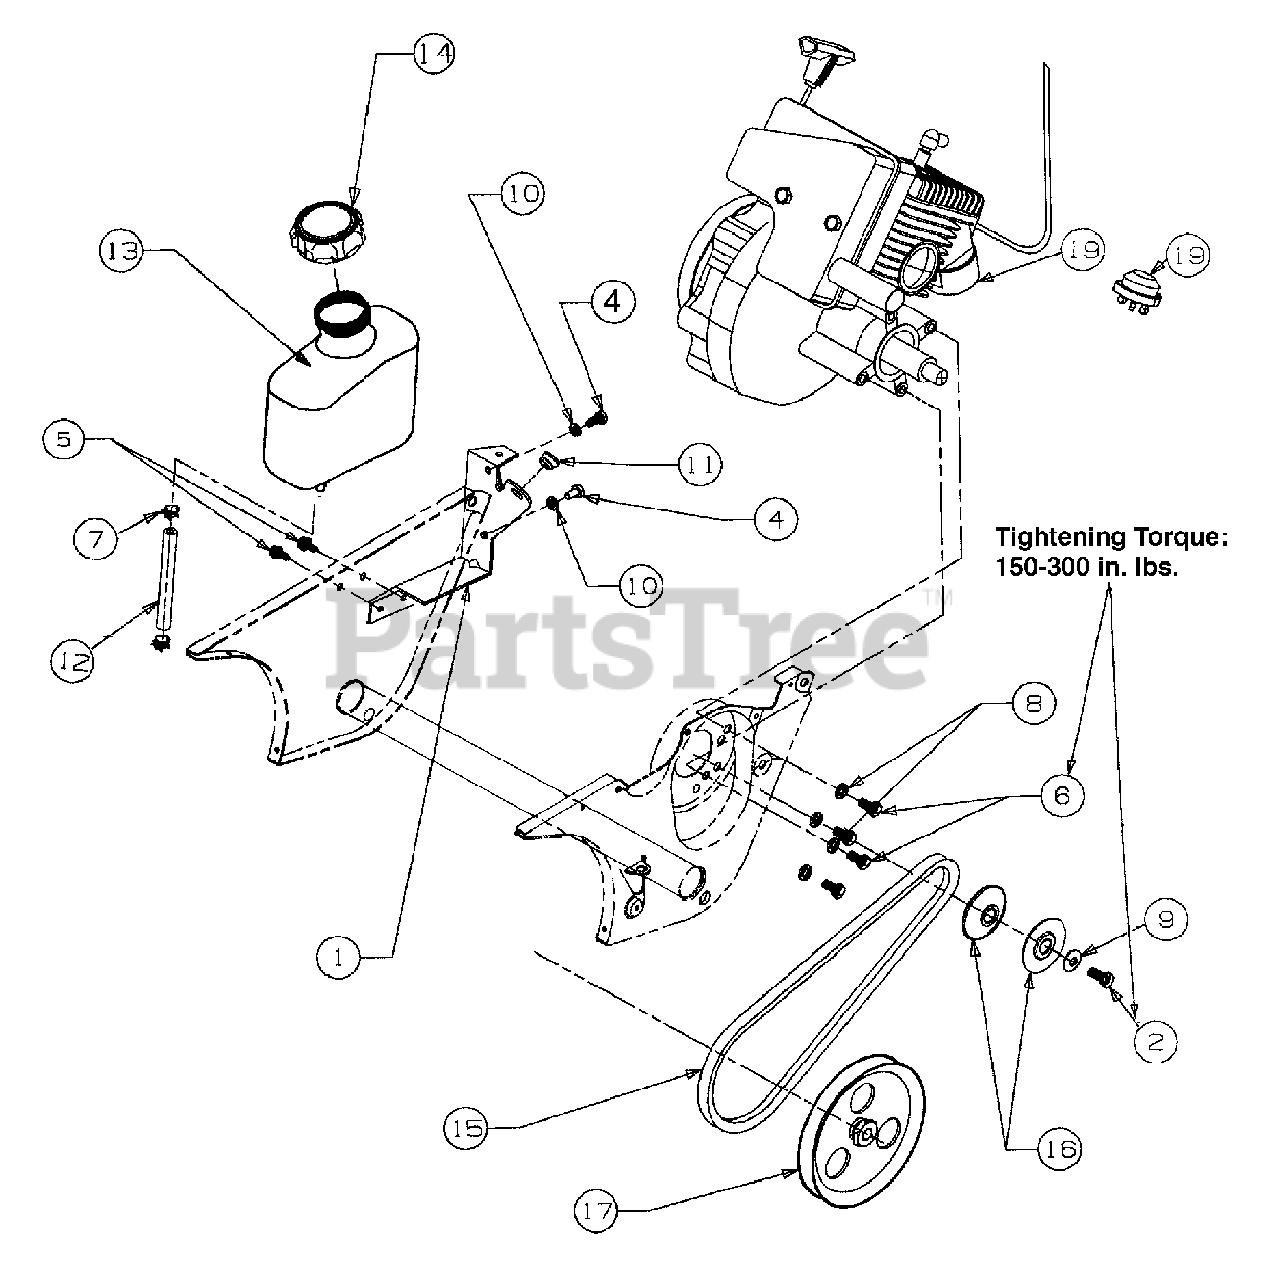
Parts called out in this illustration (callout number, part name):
1	Support Bracket, Gas Tank
2	Hex Cap Screw 5/16-24 x 0.75"
4	Hex Screw 1/4-20 x 0.50"
5	Washer Screw 1/4-14 x 0.625"
6	Hex Cap Screw 5/16-24 x 0.625"
7	Hose Clamp
8	Lock Washer
9	Bell Washer
10	Lock Washer
11	Plastic Bushing
12	Hose, Fuel Line-16"
13	Fuel Tank-2 qt.
14	Fuel Cap
15	V-Belt
16	V-Pulley Half
17	V-Pulley Half
